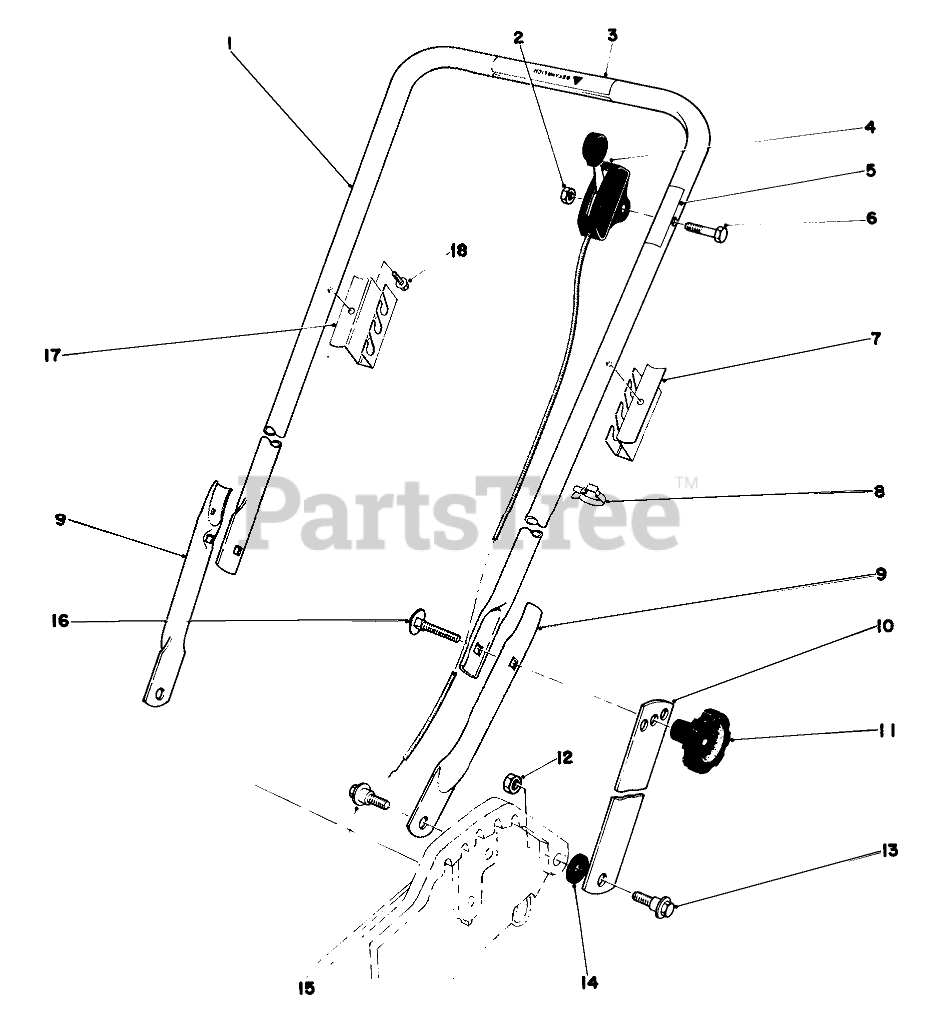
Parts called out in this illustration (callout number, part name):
1	Upper Handle (Incl. #3)
2	NUT-LOCK
3	Decal-Handle Wrap (French, English & German)
4	Throttle Control
5	Decal-Throttle
6	SCREW-HH
7	SUPPORT BAG LH
9	Hand-Lower
10	18" HANDLE LATCH
12	Locknut
13	SCREW-SHOULDER
14	SPACER
15	SCREW-SHOULDER
16	5/16-18 X 2 HNDLE SCREW
17	SUPPORT BAG RH
18	SCREW-HWHTF
